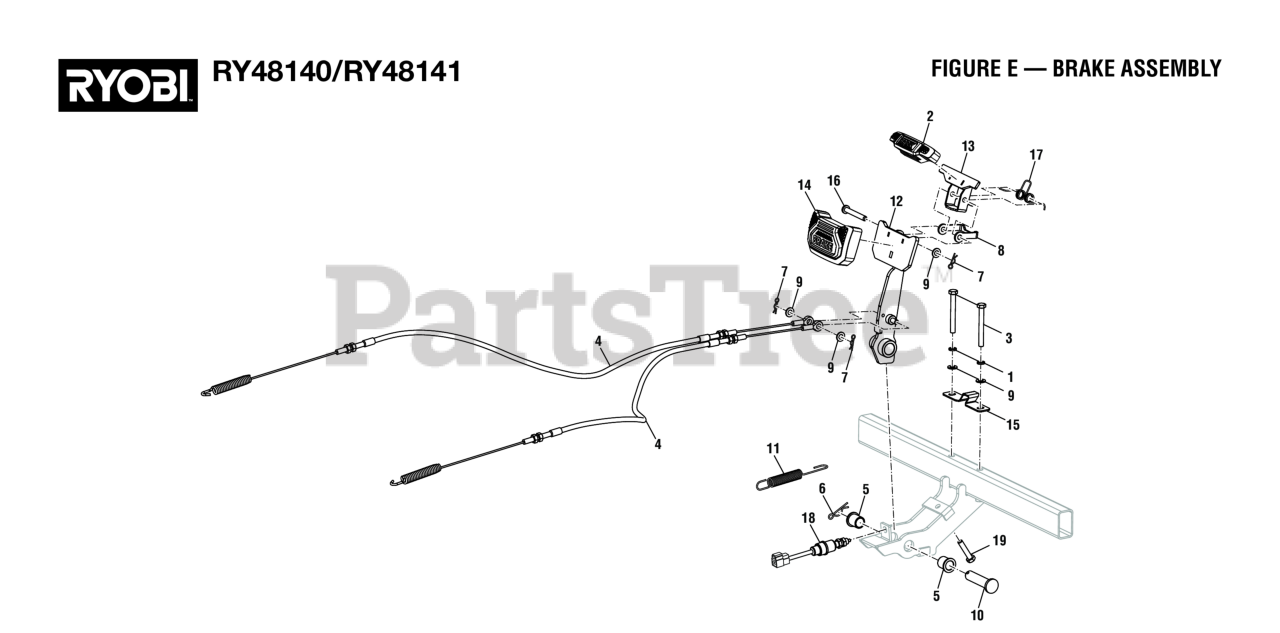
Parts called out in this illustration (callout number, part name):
1	Lock Washer (OD9.8 x ID8.5 x 5t)
2	Parking Brake Rubber Pad
3	Bolt (M8 x 70 mm, Hex Hd.)
4	Brake Cable
6	Lock Pin (16 mm)
7	Cotter Pin (8 mm)
8	Parking Brake Latch
9	Washer (OD16 x ID8.4 x 1.6t)
10	Clevis Pin
11	Brake Pedal Spring
12	Brake Pedal Lever
13	Parking Brake Pedal
14	Brake Pedal Rubber Pad
15	Brake Latch Hook
16	Clevis Pin (M8 x 60 mm)
17	Parking Brake Torsion Spring
18	Brake Switch Assembly
19	Bolt (M8 x 40 mm, Hex Hd.)
